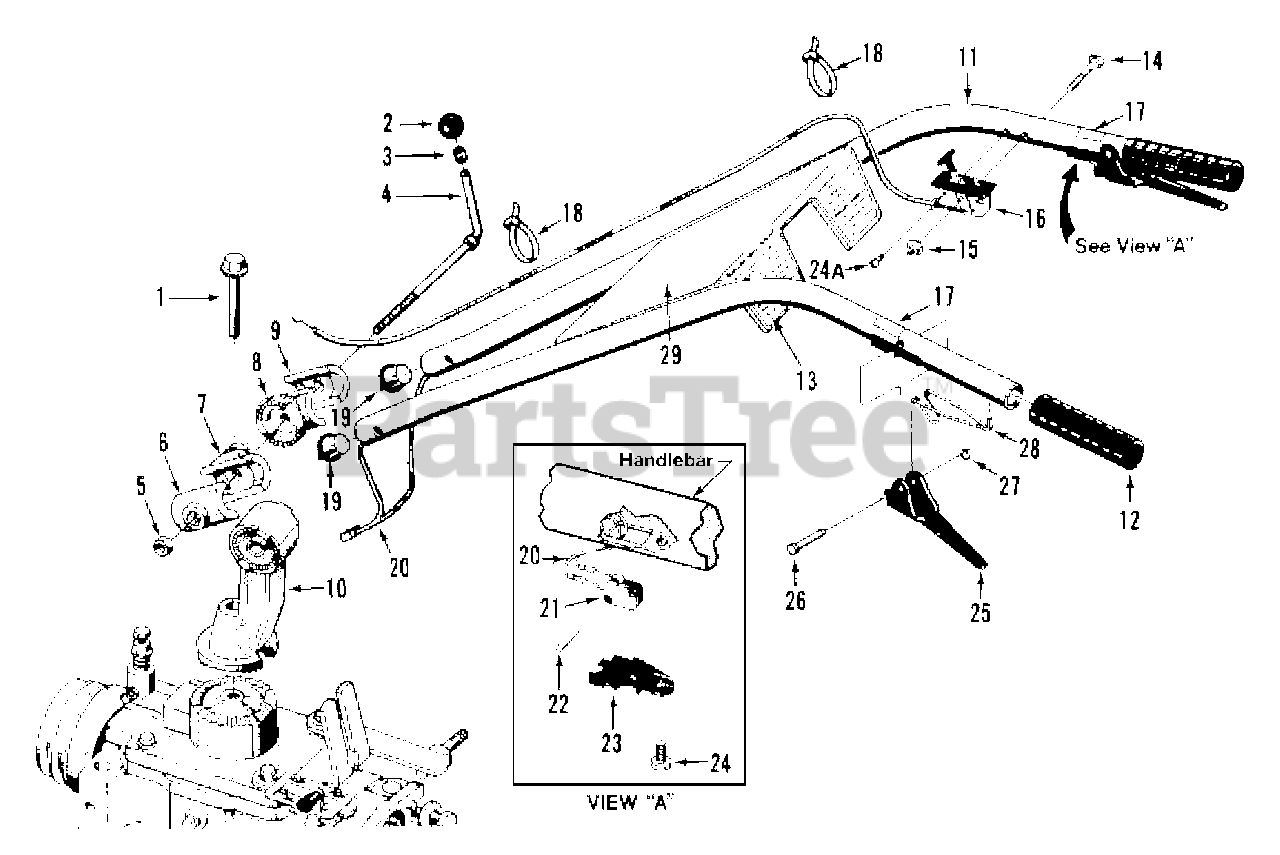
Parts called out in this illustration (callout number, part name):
1	Bolt-Hex hd., flanged self-locking Grade 5, 1/2-13 x 3-1/2"
2	Knob-handlebar height adjustment
3	Ring-retaining (tolerance ring)
4	Stud-handlebar height adjustment
5	Nut-hex, 1/2"-13
6	Clamp-left, handlebar height adjustment
7	Ratchet-left, handlebar height adjustment
8	Ratchet-right, handlebar height adjustment
9	Clamp-right, handlebar height adjustment
10	Base-handlebar mounting
12	Grip-handlebars
13	Decal-Control panel
14	Bolt-curved hd, GR5, 1/4-20 x 2"
15	Nut-hex, flanged self-locking, whiz lock, 1/4"-20
16	Throttle Control & Cable, 66"
17	Decal-Forward Interlock Lever
18	Tie-plastic
19	Plug-wire harness retainer
20	Handlebar Wire Harness Assy-forward interlock system
21	Handlebar Switch-forward interlock system
22	Lock Pin-handlebar switch
23	Switch Housing-handlebar switch.
24	Screw-pan head, 10-24 x 1/2", thread-forming
24A	Screw-phillips head, 10-32 x 1/2", thread-forming
26	Pivot Pin-forward interlock lever
27	Retaining Ring-klip ring-forward interlock lever
28	Return Spring-fwd interlock lever.
29	Label - Troy-Bilt Horse
